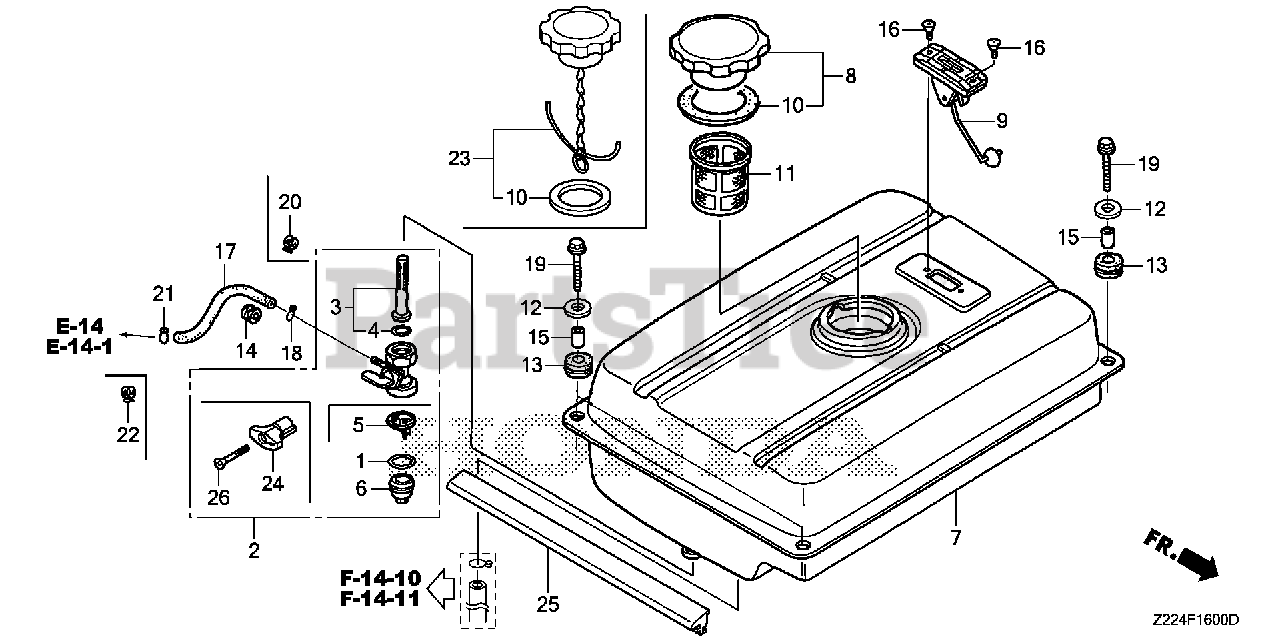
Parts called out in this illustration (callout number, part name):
1	GASKET, FUEL STRAINER CUP
2	PETCOCK ASSY.
3	SCREEN SET, FUEL STRAINER
4	O-RING (9.0X1.3)
6	CUP, FUEL STRAINER
7	TANK, FUEL *R280* (POWER RED)
9	METER ASSY., FUEL
10	GASKET, FUEL FILLER CAP
11	FILTER, FUEL
12	WASHER (6MM)
13	CUSHION, TANK RUBBER
14	RUBBER, FUEL (9X15X20)
15	COLLAR, TANK CUSHION
16	SCREW, FLAT (5X10)
17	TUBE, FUEL (4.5X165)
19	BOLT, FLANGE (6X22)
20	CLIP, TUBE (D8)
22	CLIP, TUBE (D8.5)
23	CAP, FUEL FILLER
24	LEVER, PETCOCK
25	RUBBER, FUEL TANK
26	SCREW, OVAL (4X18)
